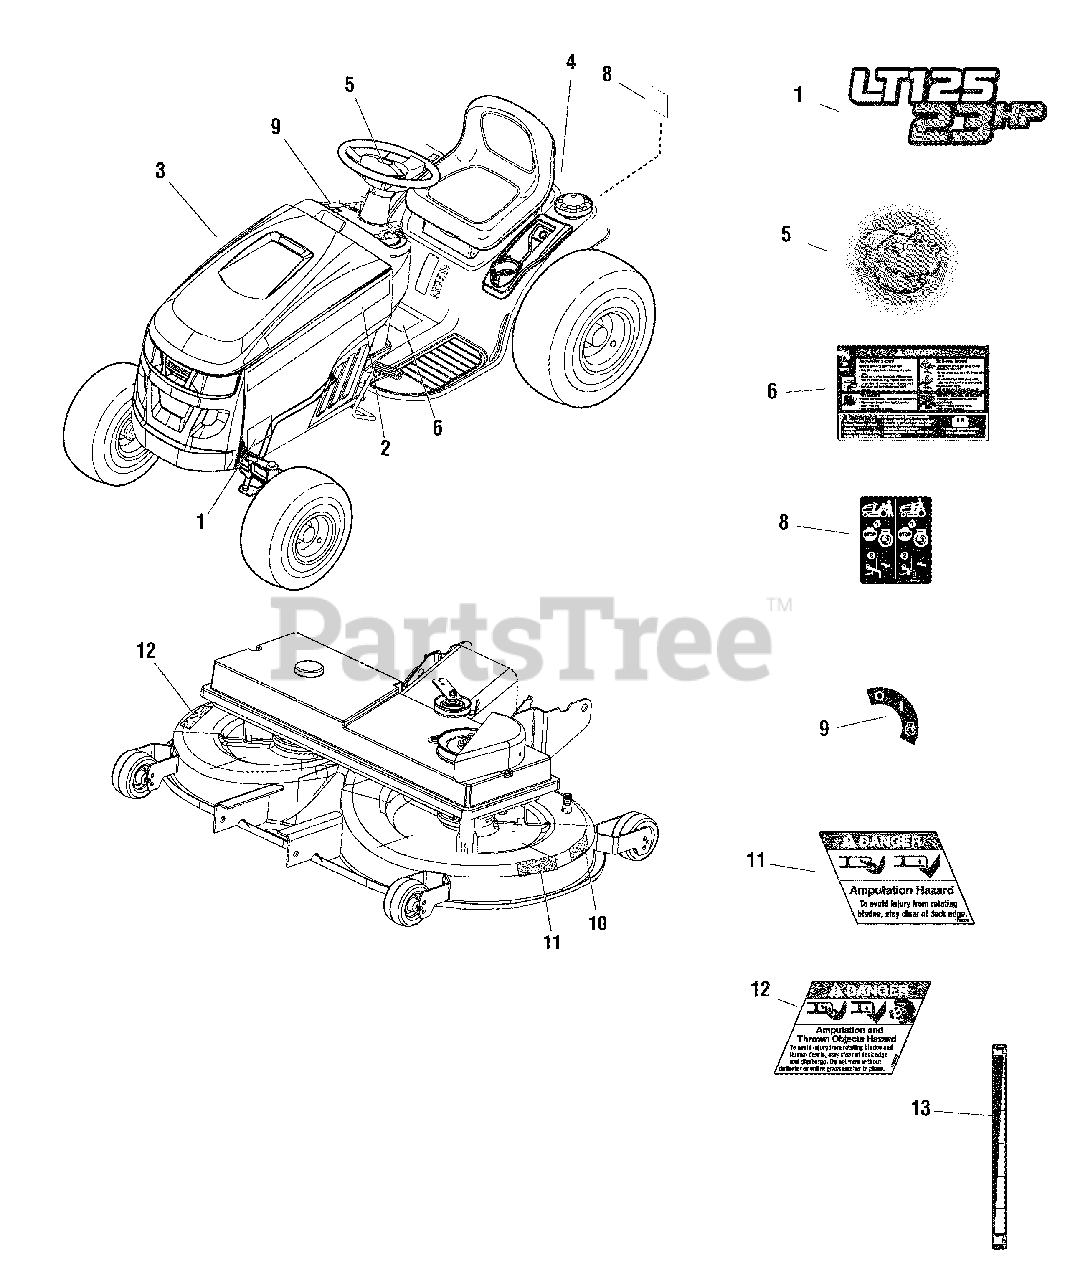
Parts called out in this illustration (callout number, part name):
1	DECAL, 23HP Snapper
2	DECAL, Snapper LH Stripe
3	DECAL, Snapper RH Stripe
4	DECAL, Snapper Rear
5	DECAL, Snapper Steering Wheel
6	DECAL, Tunnel
8	DECAL, Trans/Tow Release Lever
9	DECAL, Ignition Switch White/Blk
10	DECAL, 42" Deck
11	DECAL, Danger Blades
12	DECAL, Danger, Do No Operate without Deflector
13	DECAL, Mower Height
